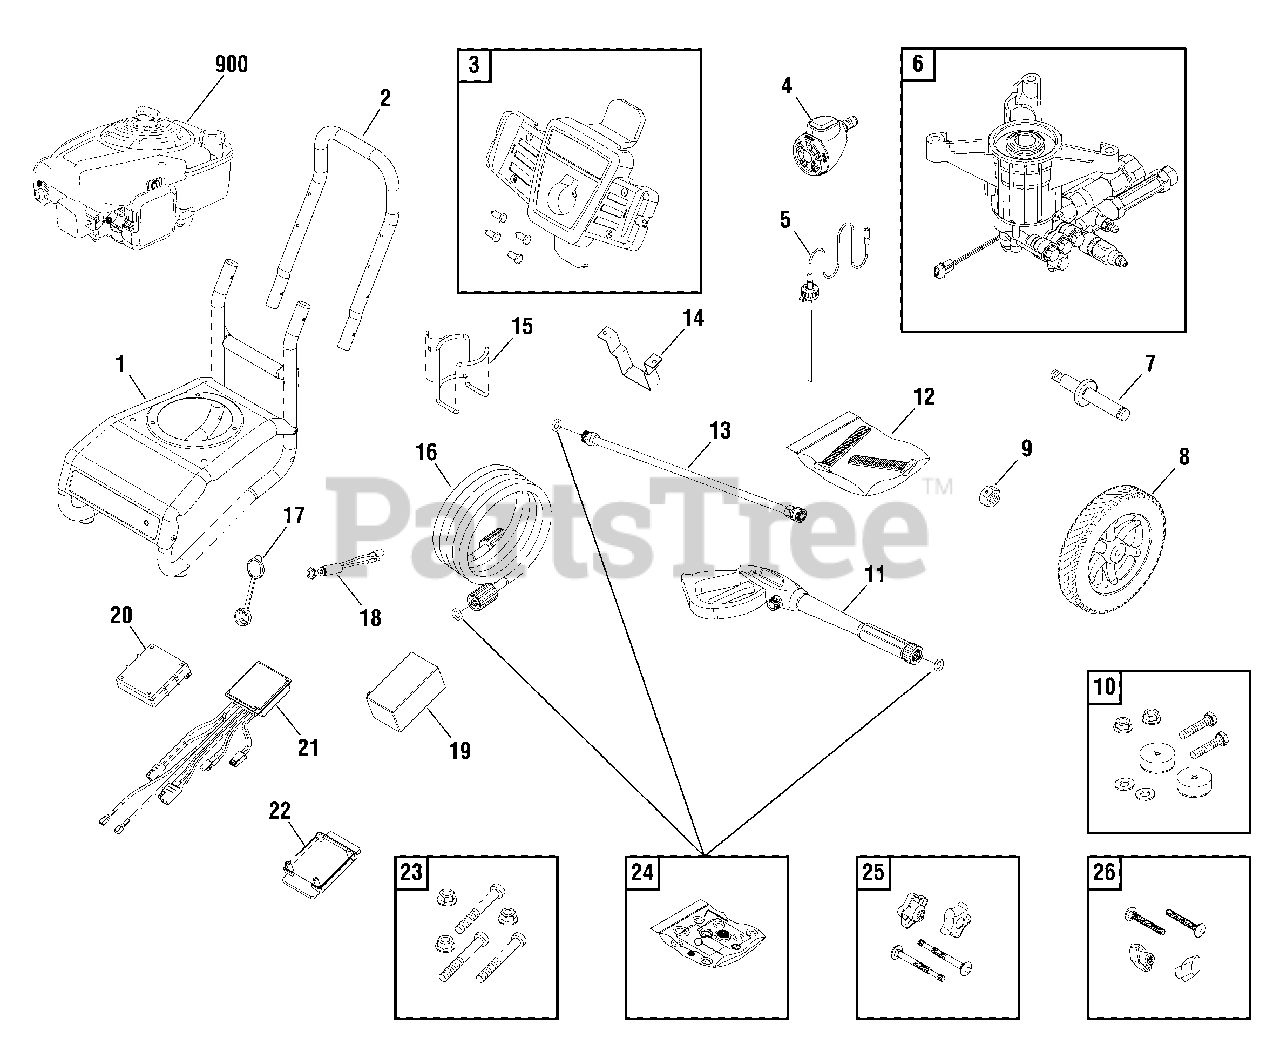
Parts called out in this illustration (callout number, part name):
10	MOUNT-VIBRATION
11	GUN
16	HOSE
21	CIRCUIT BOARD
23	KIT-HARDWARE PUMP MOUNTING
900	** ENGINE
